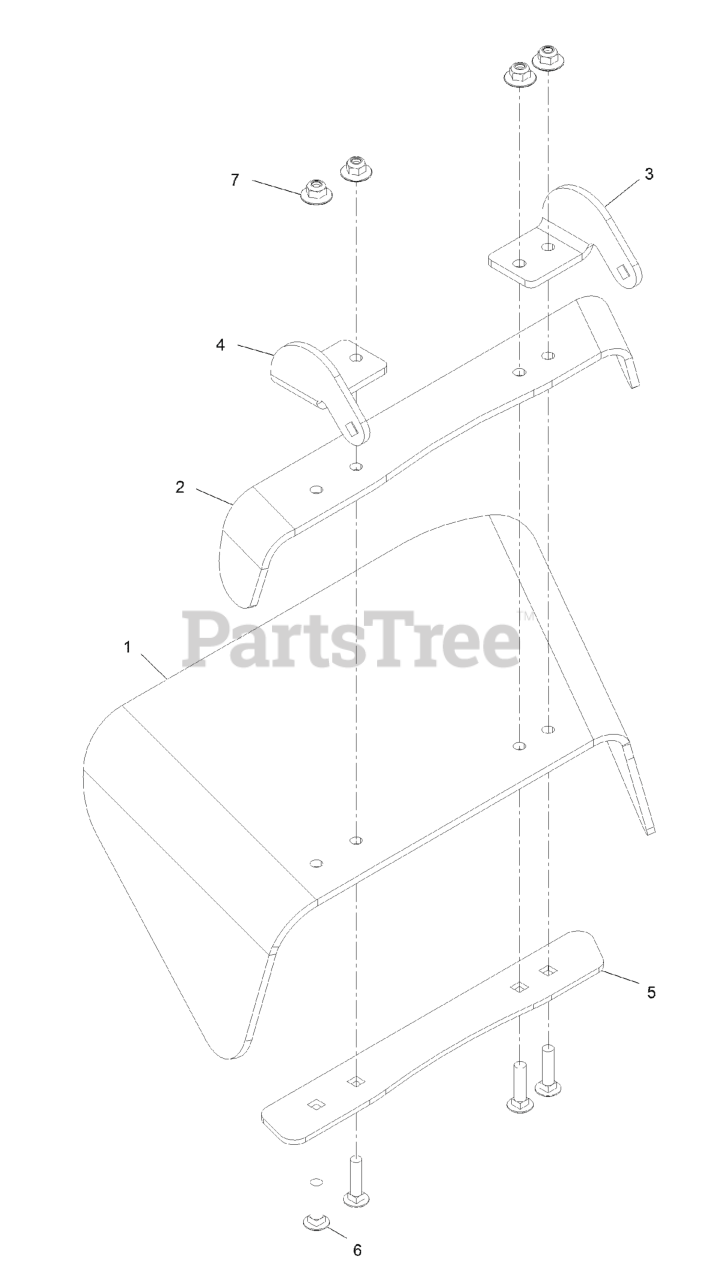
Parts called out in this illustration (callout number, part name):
1	DEFLECTOR-RUBBER
2	BRACKET-TOP DEFLECTOR
3	BRACKET-DEFLECTOR
4	BRACKET-DEFLECTOR
5	STRAP-BOTTOM DEFLECTOR
6	SCREW-CARR
7	Nut-Nyloc 3/8-16 Flg
